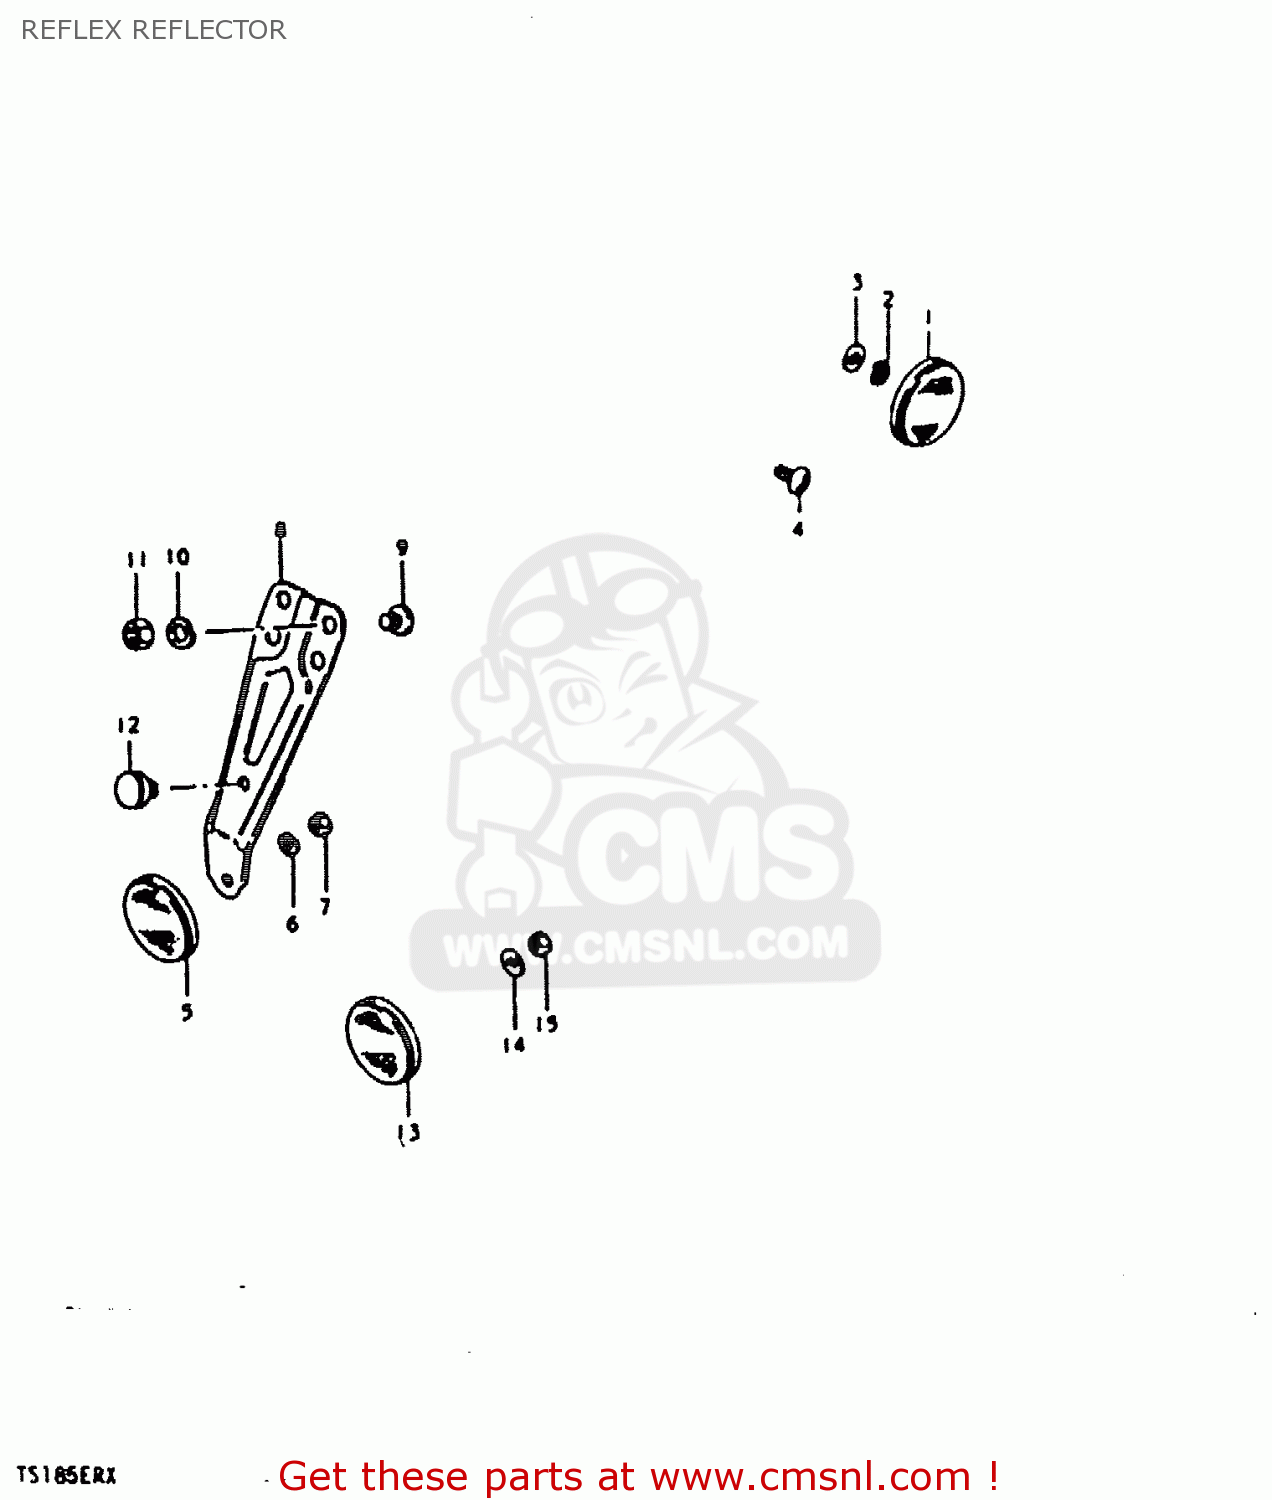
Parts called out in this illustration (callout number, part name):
1	REFLEX REFLECTOR,FR
2	LOCK WASHER
3	WASHER
5	REFLEX REFLECTOR,RR
6	WASHER
7	NUT
8	BRACKET
9	SCREW
10	LOCK WASHER
11	NUT
12	CUSHION
